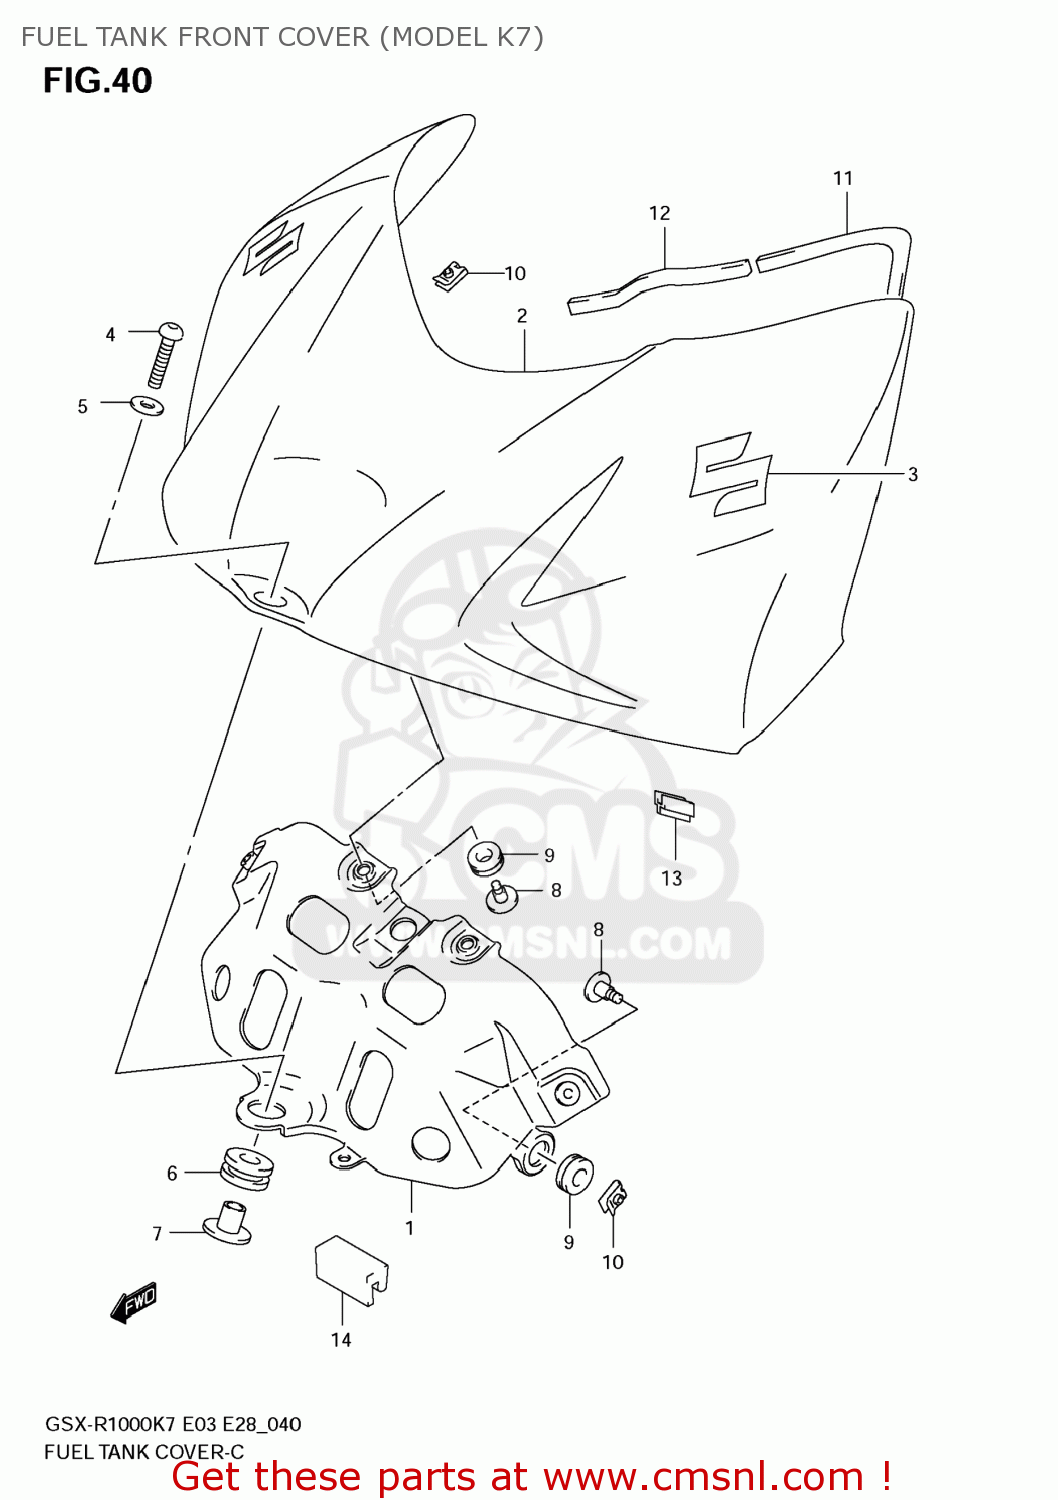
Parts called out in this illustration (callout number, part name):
1	BRACKET,FUEL TANK FR
2	COVER,FUEL TANK FR
3	EMBLEM,S
4	BOLT(8X37)
5	WASHER(8.5X20X1.6)
6	CUSHION
7	SPACER(8.6X12X16.1)
8	SCREW(5X16.4)
9	CUSHION
10	NUT
11	CUSHION,FUEL TANK COVER
12	CUSHION,TANK COVER
13	CUSHION,FUEL TANK COVER
14	MOLDING
